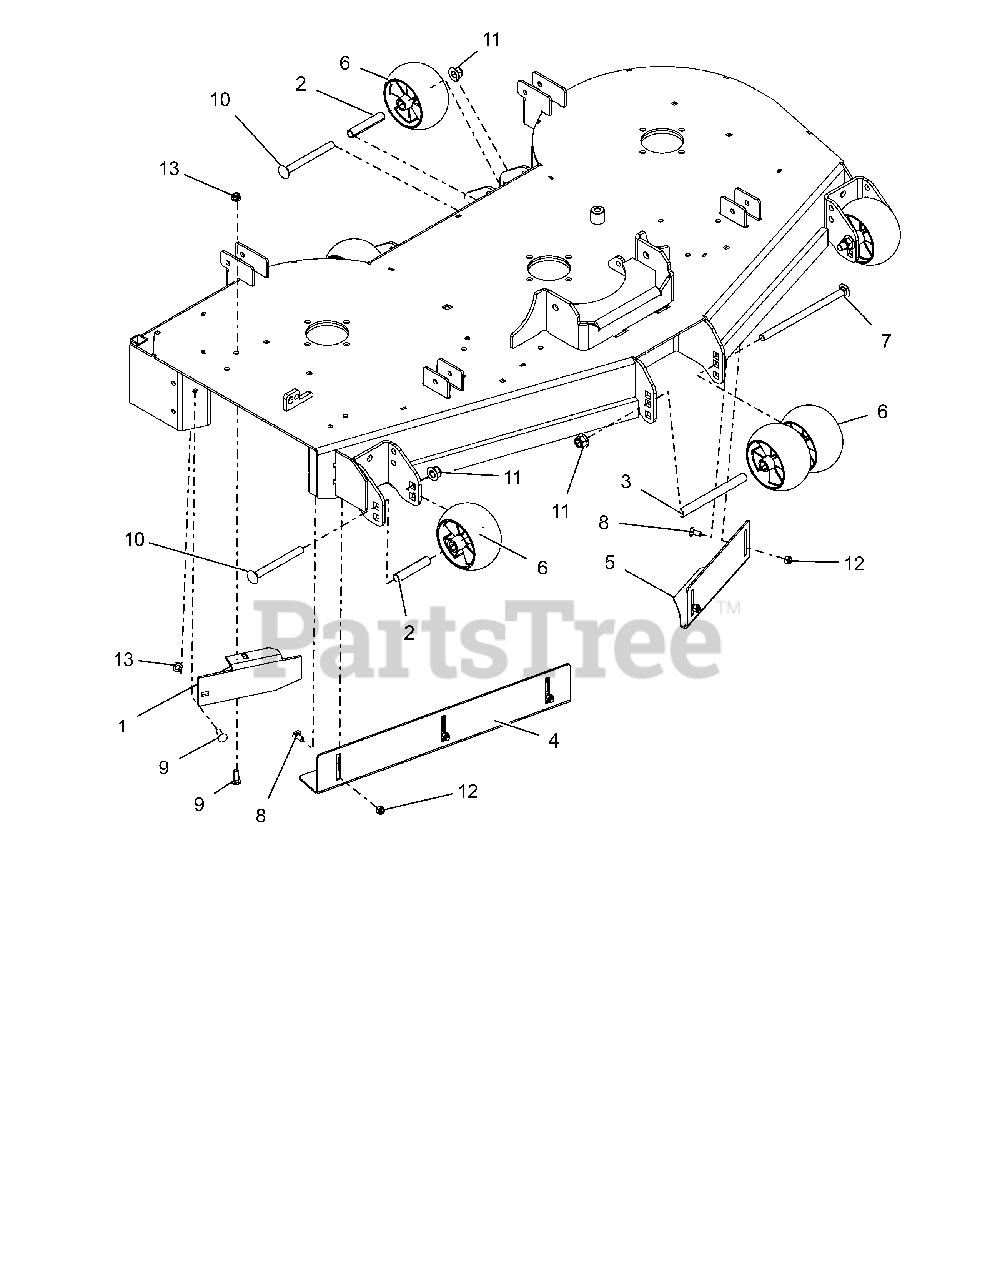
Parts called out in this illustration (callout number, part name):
1	52" DISCHARGE BAFFLE - RED
2	SPACER, .510X.625X3.35
3	SPACER, .510X.625X6.50
4	52" RH VACCUM BAFFLE - RED
5	52" LH VACUUM BAFFLE - RED
6	ANTI-SCALP WHEEL - 5X3 CTR
7	@BLT-RDHDSQNK .50-13X8.50 G5YZ
8	@BLT-RDHDSQNK .31-18X.75 G5YZ
9	@BLT-RDHDSQNK .31-18X1.00 G5YZ
10	BLT-RDHDSQNK .50-13X5.00 GR5YZ
11	@NUT-LK-NYL-FLG .50-13 YWZC
12	@NUT-LK-NYL .312-18 YWZC
13	@NUT-LK-NYL-FLG .31-18 YWZC
